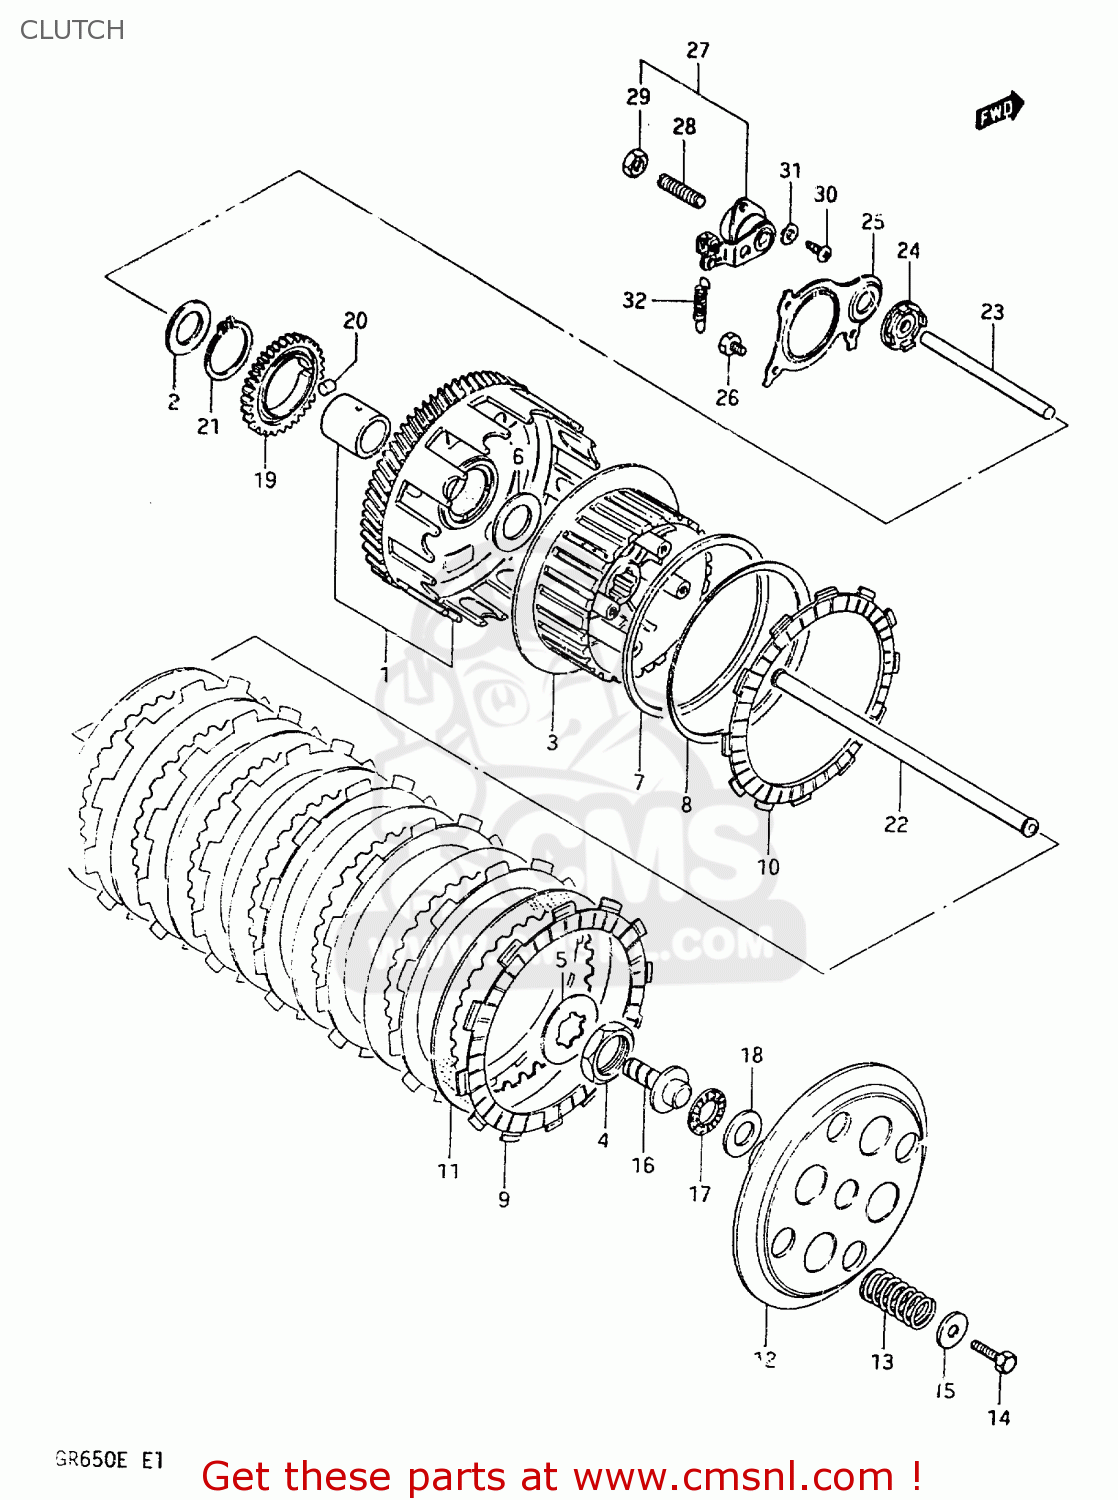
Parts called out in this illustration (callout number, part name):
1	GEAR ASSEMBLY,PRIMARY DRIVE
2	WASHER
3	HUB,CLUTCH SLEEVE
4	NUT
5	WASHER,LOCK
6	WASHER (22X40X1.5)
7	SEAT,WAVE WASHER(T:1.4)
8	WASHER
9	PLATE,CLUTCH DRIVE (NAS)
10	PLATE,CLUTCH DRIVE
11	PLATE,CLUTCH DRIVEN
12	DISC,CLUTCH PRESSURE
13	SPRING
14	BOLT, UPPER
15	WASHER
16	PIECE,CLUTCH PUSH
17	BEARING(15X28X2)
18	WASHER
19	GEAR,OIL PUMP DRIVE
20	PIN(6X6)
21	CIRCLIP
22	ROD,CLUTCH PUSH
23	ROD,CLUTCH PUSH,L
24	SEAL,OIL(6X34X10)
25	PLATE,CLUTCH PUSH ROD
26	BOLT
27	SCREW ASSEMBLY,RELEASE
28	SCREW
29	NUT 6MM
30	SCREW
31	WASHER
32	SPRING
